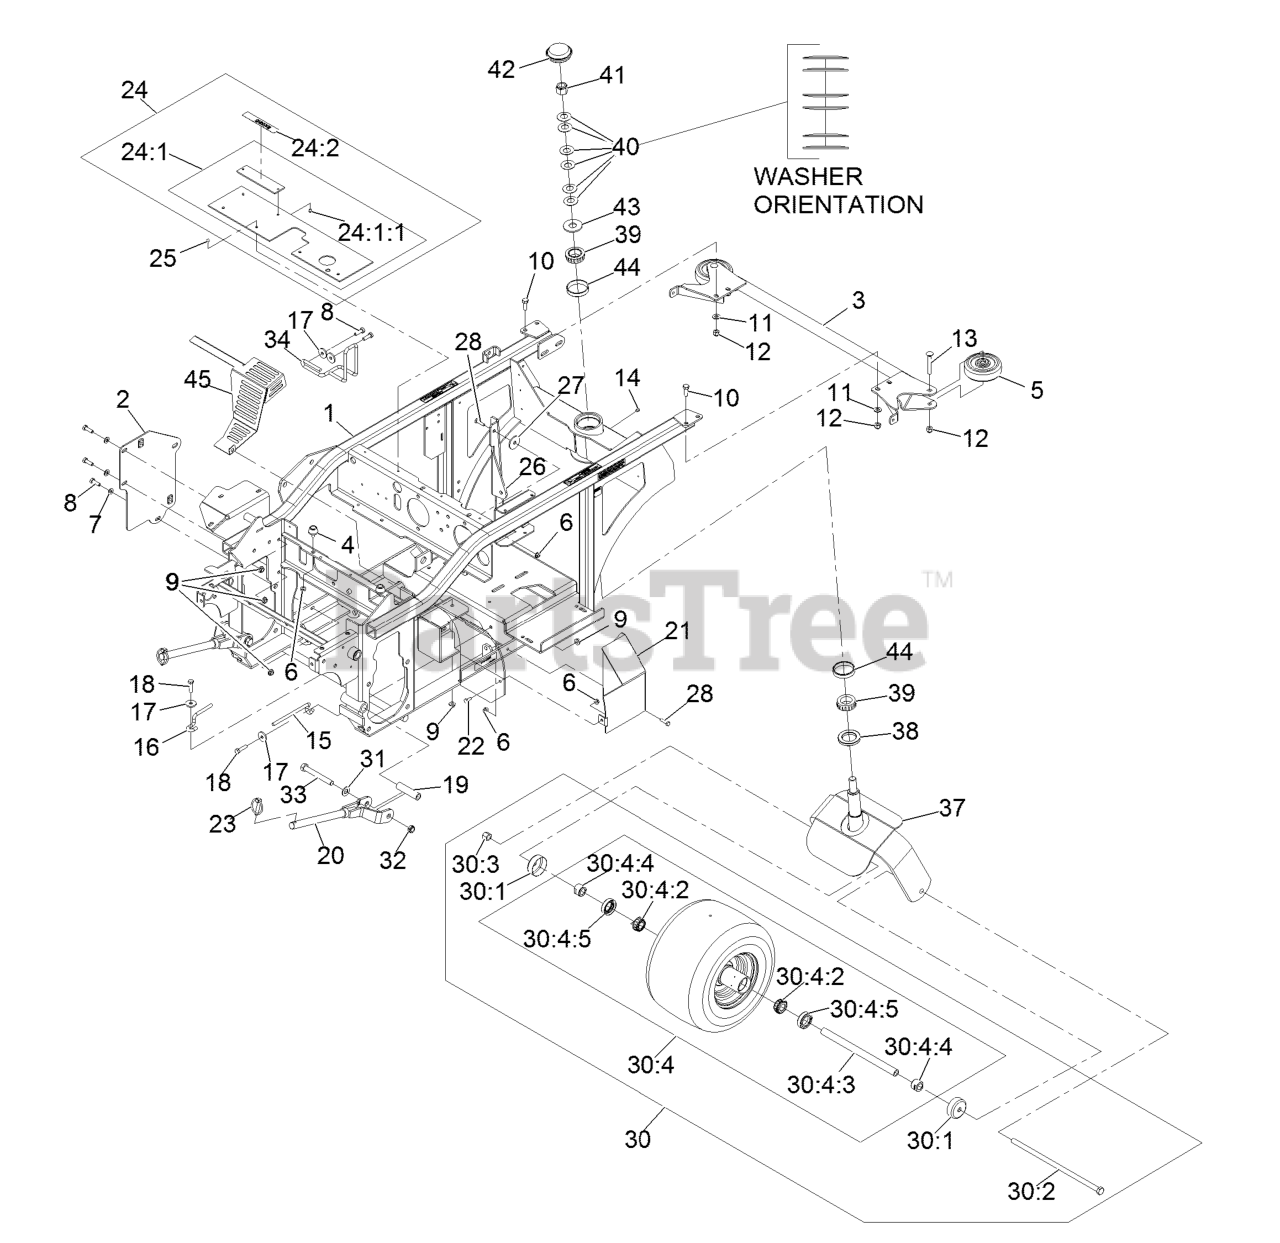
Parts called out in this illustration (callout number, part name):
1	FRAME ASM
2	PLATE-SUPPORT
3	BUMPER-REAR
4	BUMPER-RUBBER
5	ROLLER-BUMPER
7	WASHER-PLAIN
8	SCREW-HH
10	SCREW-HH
11	WASHER-FLAT
12	NUT-LOCK, NI
13	SCREW-CARR
15	GUIDE-BELT
16	GUIDE-BELT
18	SCREW-HH
19	SPACER-WHEEL, SHORT
22	SCREW-HH
23	PIN-LYNCH
24	LIFT SHIELD ASM
24:1	Asm,Shield Lift
24:1:1	Rivet 3/16 X 1/4
24:2	DECAL-WARNING
25	Rivet 3/16 X 1/4
26	BRACE-PTO
27	Washer
28	SCREW-HH
30	REAR CASTER WHEEL ASM
30:1	GUARD-SEAL
30:2	SCREW-HH
30:3	NUT-LOCK, NI
30:4	ASM,WHEEL,TIRE & BRG SP
30:4:2	BEARING-CONE, TAPERED ROLLER
30:4:4	SPACER-NUT
30:4:5	SEAL-CASTER
31	WASHER-FLAT
32	NUT-HEX
33	SCREW-HH
34	GUIDE-BELT
37	FORK-REAR CASTER
38	SEAL-GREASE
39	BEARING-ROLLER, CONE TAPE
40	WASHER-BELLVILLE
41	NUT-LOCK, NI
42	CAP-GREASE
43	WASHER-FLAT
44	CUP-TAPERED, ROLLER BEARI
45	SHIELD-HEAT
